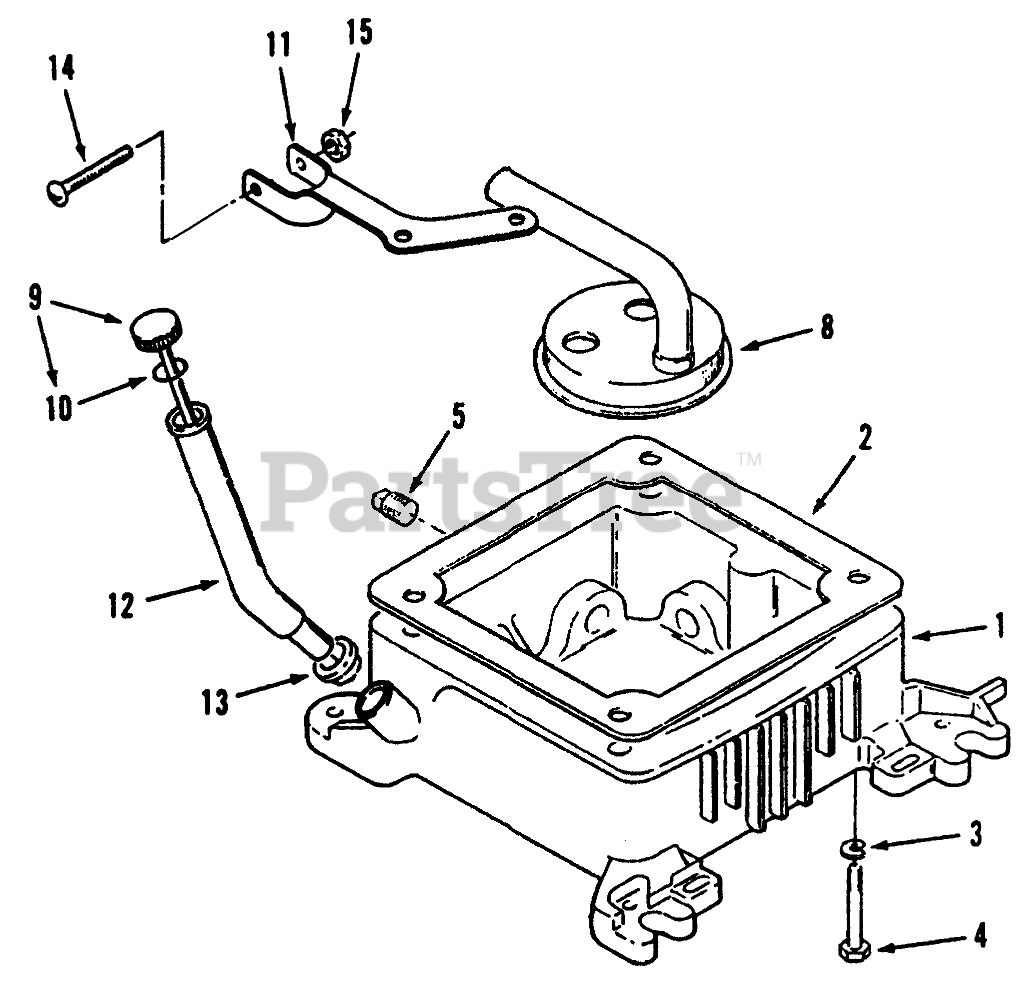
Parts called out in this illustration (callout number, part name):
1	Base-Oil (Incl. All Plugs & Plug Gasket)
2	GASKET
3	WASHER-FLAT
4	HHCS 3/8-16 X 3 3/4
5	PLUG - SQUARE HEAD
8	Cup-Oil Pump Intake
9	Cap-Oil Fill & Indicator (Incl. "O" Ring)
10	O-Ring
11	BRACKET-FILL TUBE
12	TUBE-OIL FILL
13	Seal
14	SCREW - PAN HEAD
15	NUT - SPEED
